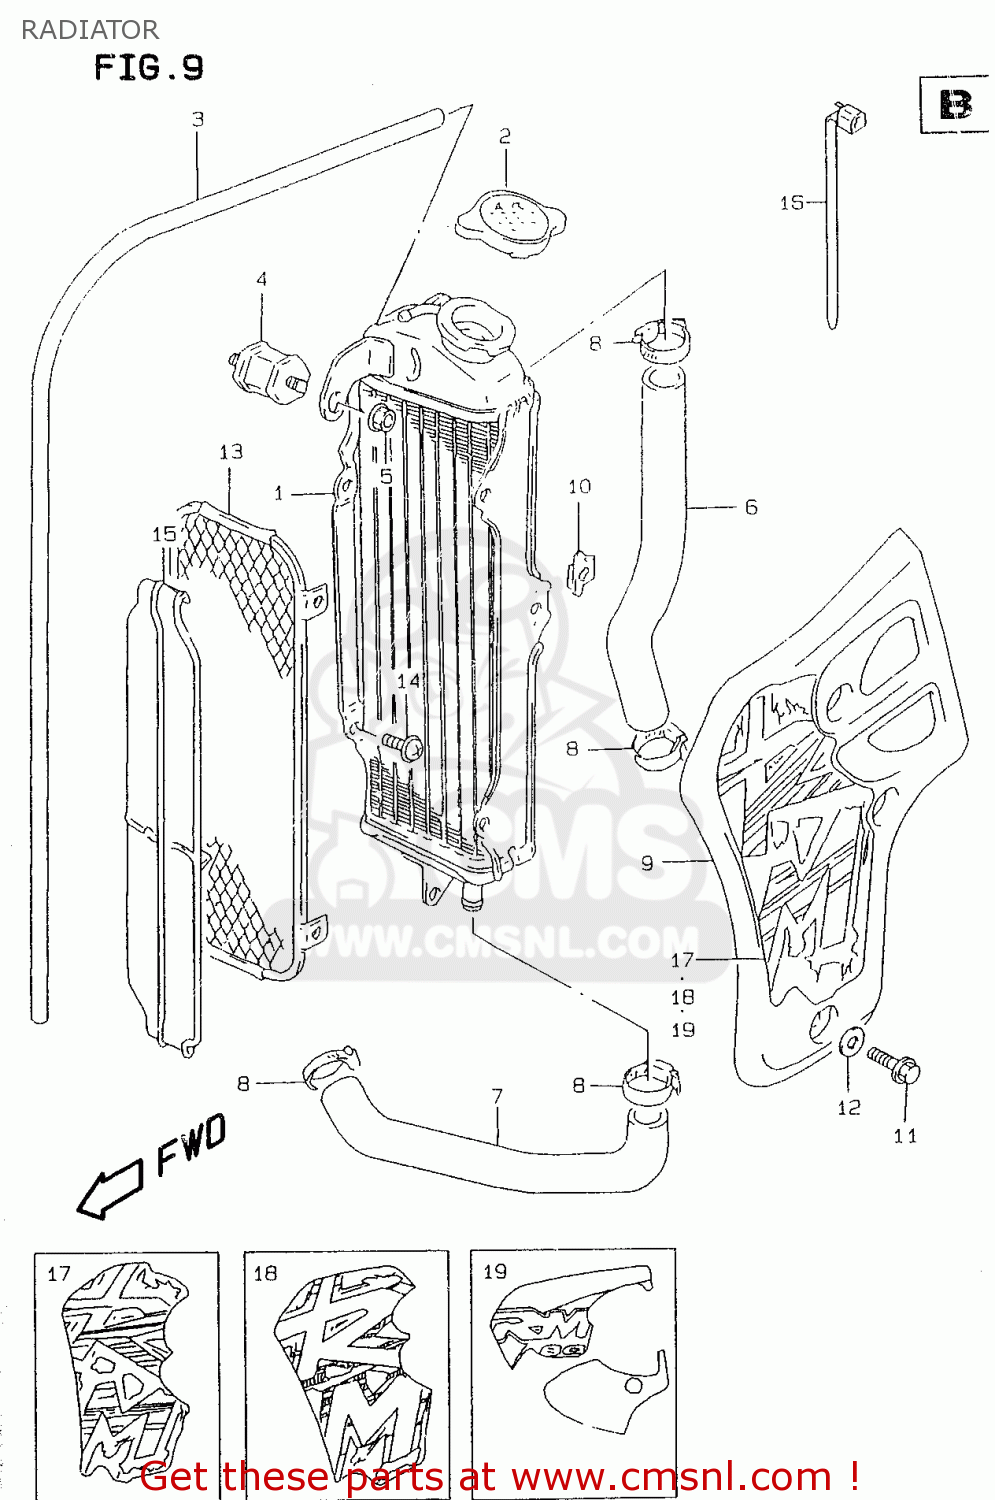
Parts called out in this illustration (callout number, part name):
1	RADIATOR COMP,WATER
2	CAP,RADIATOR
3	HOSE (5X8X600)
4	BOLT,RADIATOR CUSHION
5	NUT
6	HOSE,RADIATOR INLET
7	HOSE,RADIATOR OUTLET
8	CLAMP
9	COVER,RADIATOR
10	PLATE,RADIATOR COVER FITING
11	BOLT
12	WASHER(6.5X18X1)
13	BUMPER,RADIATOR
14	SCREW
15	COVER,RADIATOR
16	CLAMP(L:235)
17	EMBLEM,RADIATOR COVER
18	EMBLEM,RADIATOR COVER
19	TAPE SET,RADIATOR COVER
